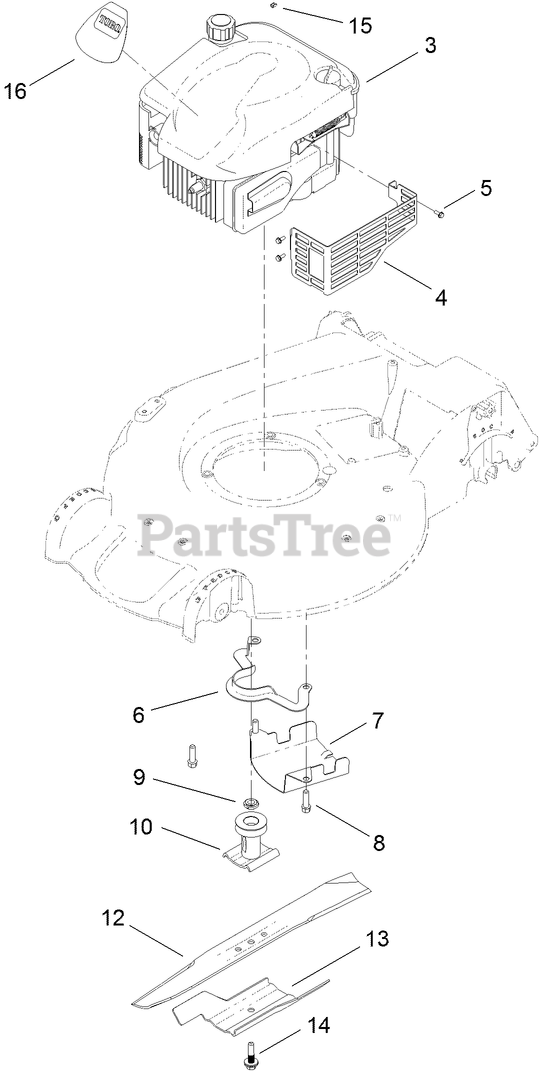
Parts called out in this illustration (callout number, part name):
4	SHIELD-MUFFLER
5	SCREW-TAPTITE
6	GUIDE-BELT
7	SHIELD-GRASS
8	SCREW-TAPTITE
9	Spacer-Driver
10	DRIVER-BLADE
12	BLADE-RECYCLING
13	Accelerator-Blade
14	BOLT-BLADE
15	STOP-ROPE
16	DECAL-SHROUD
